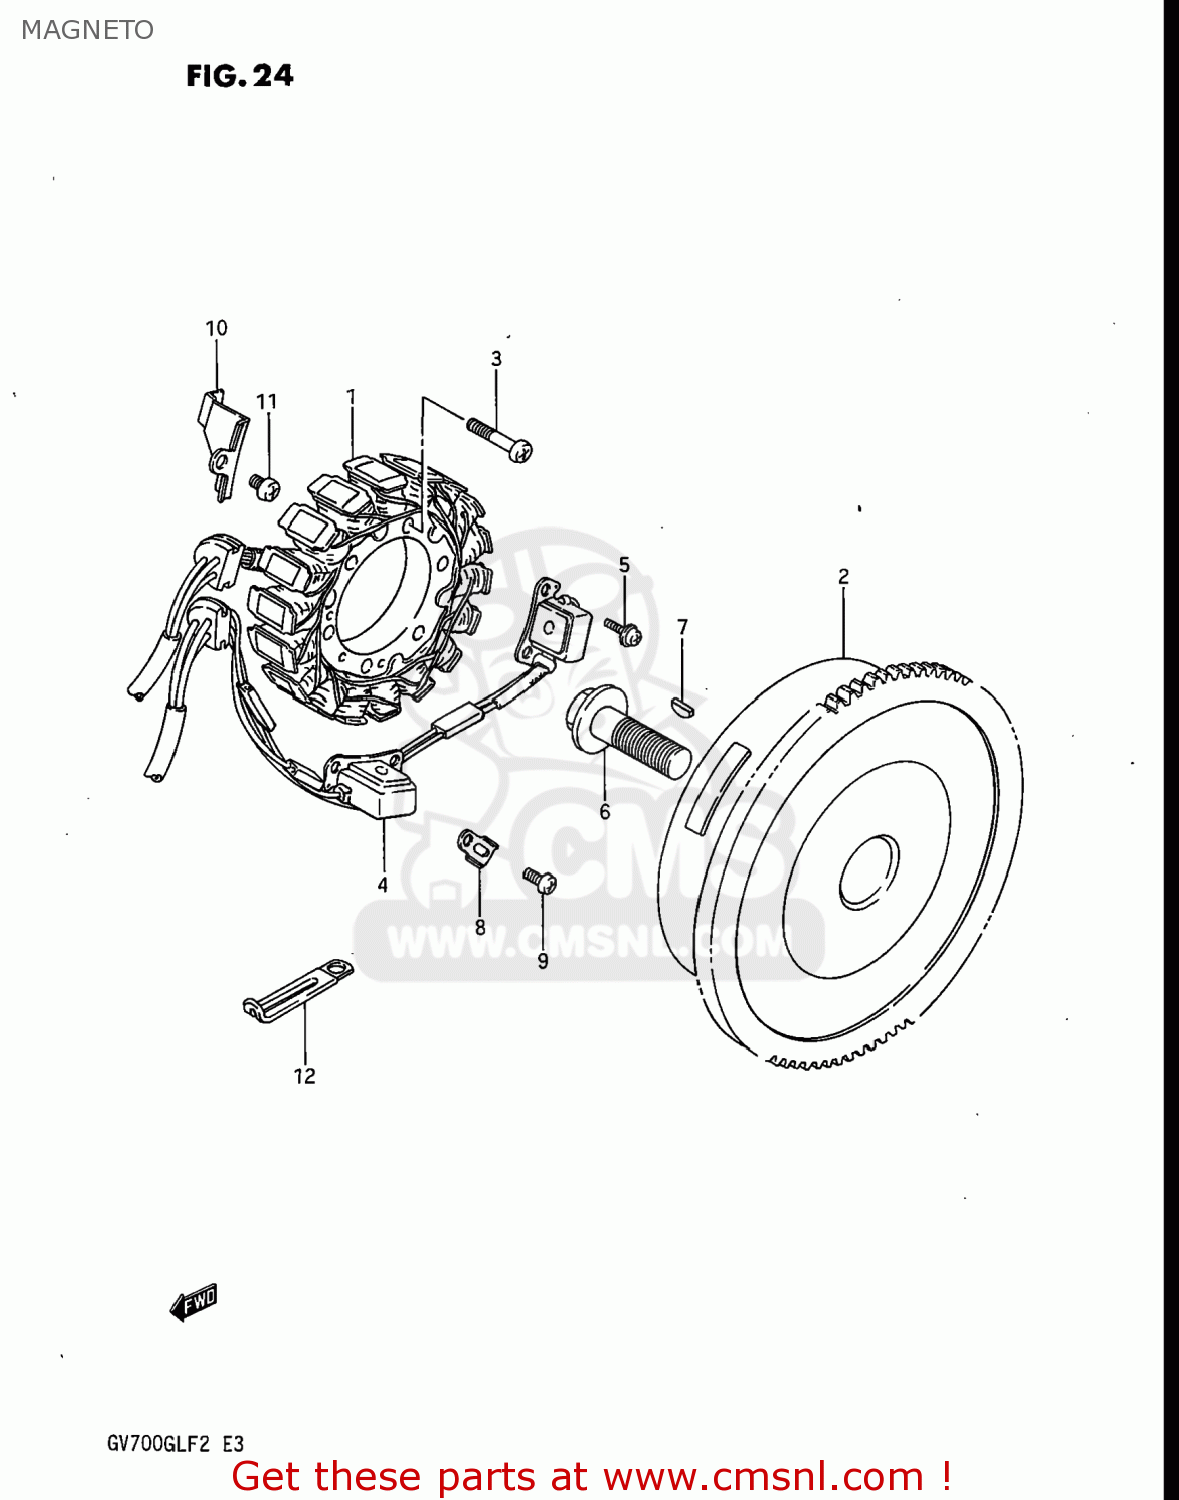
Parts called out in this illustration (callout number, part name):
1	STATOR ASSEMBLY,AC
2	ROTOR ASSEMBLY
3	SCREW 6X30
4	SENSOR ASSEMBLY,TIMING
5	SCREW
6	BOLT(14X43)
7	KEY 4MM
8	CLAMP,GENERATOR LEAD WIRE
9	SCREW
11	SCREW
12	CLAMP
